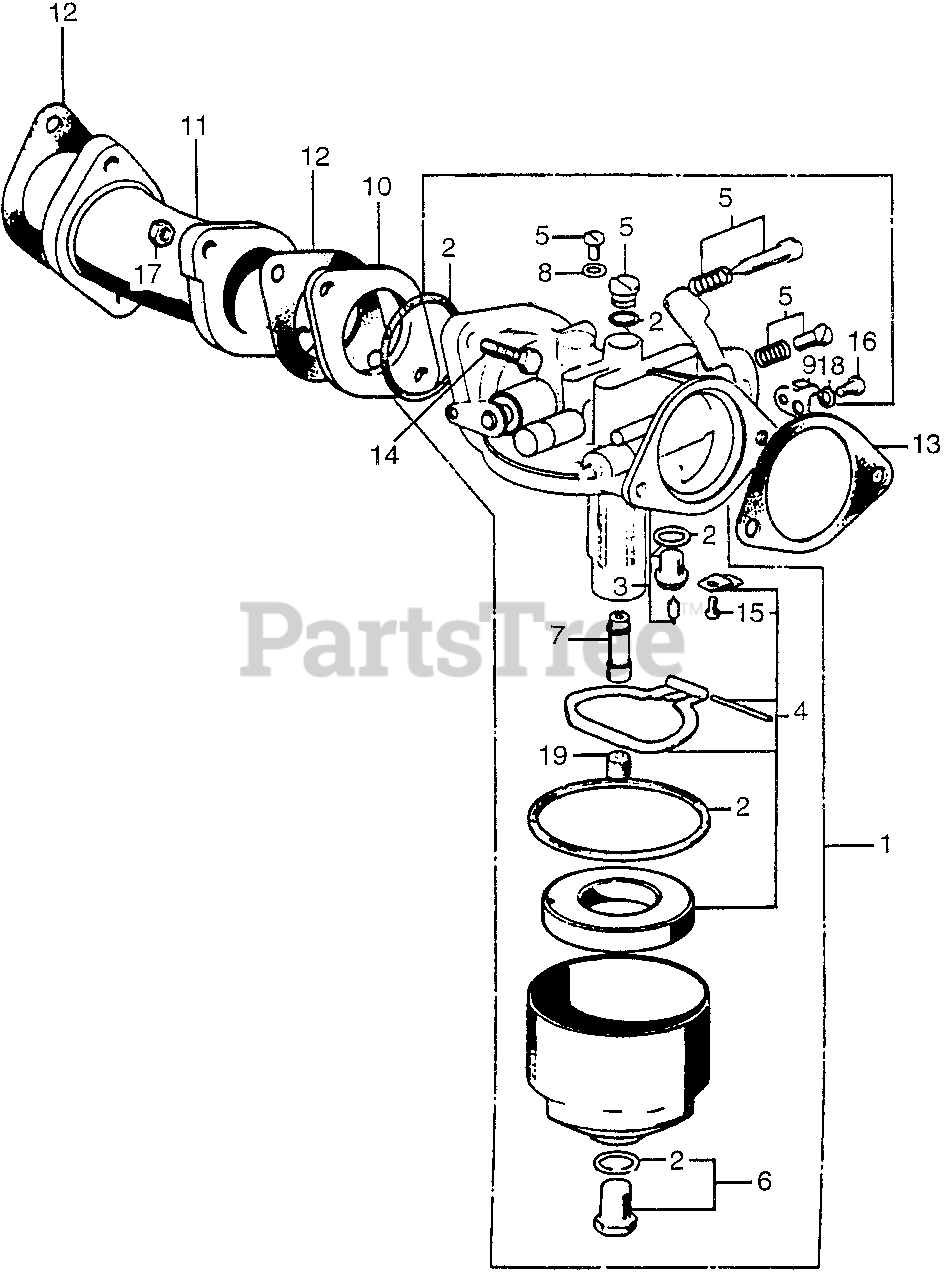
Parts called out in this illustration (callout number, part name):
1	CARBURETOR ASSY. (NOT AVAILABLE)
2	GASKET SET
3	VALVE SET, FLOAT
4	FLOAT SET
5	SCREW SET A (NOT AVAILABLE)
6	SCREW SET (NOT AVAILABLE)
7	NOZZLE, MAIN (NOT AVAILABLE)
8	WASHER, SPRING
9	PLATE, CLICK
10	INSULATOR, CARBURETOR (NOT AVAILABLE)
11	ELBOW, CARBURETOR (NOT AVAILABLE)
12	GASKET, CARBURETOR ELBOW
13	GASKET, AIR CLEANER (NOT AVAILABLE)
14	BOLT, HEX. (6X20)
15	SCREW, PAN (3X5)
16	SCREW, PAN (3X8)
17	NUT, HEX. (6MM)
18	WASHER, SPRING (3MM)
19	JET, MAIN (#72)
19	JET, MAIN (#78) (NOT AVAILABLE)
19	JET, MAIN (#80)
19	JET, MAIN (#82)
19	JET, MAIN (#75)
